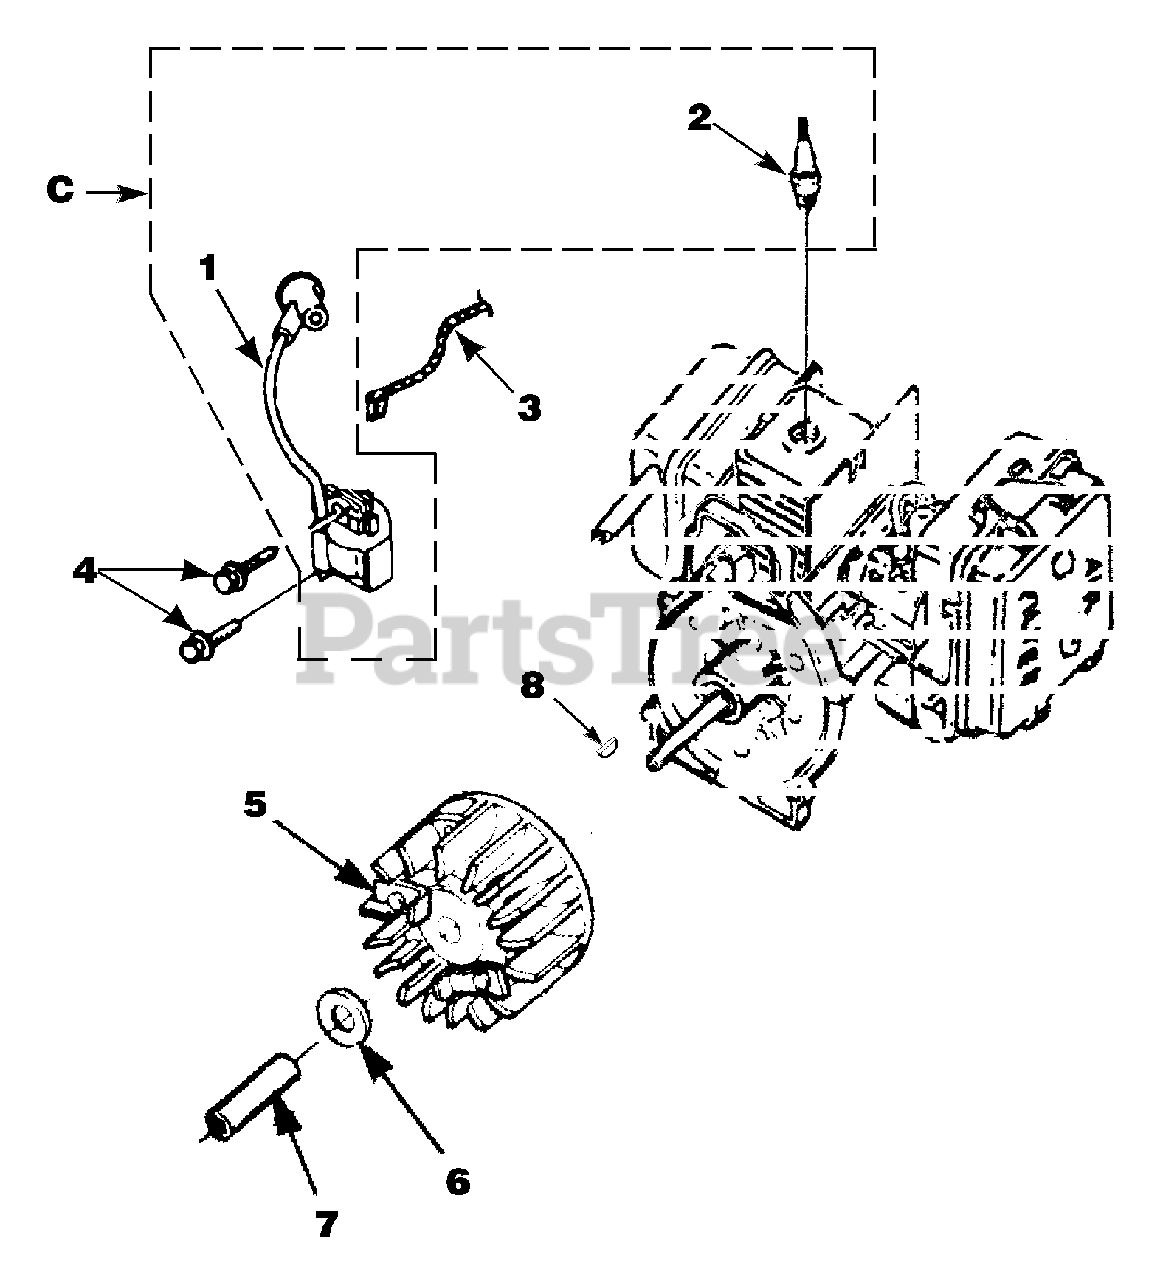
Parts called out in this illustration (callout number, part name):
1	TERMINAL-Hi-Tension
2	SPARK PLUG (RDJ-7Y)
3	LEAD-Electrical
4	SCREW-Thread Form. (8-32 x 1")
5	ROTOR & STARTER PAWLS
6	WASHER-Flat
7	SPACER-Fan
8	KEY-Woodruff
C	IGNITION KIT w/Module
